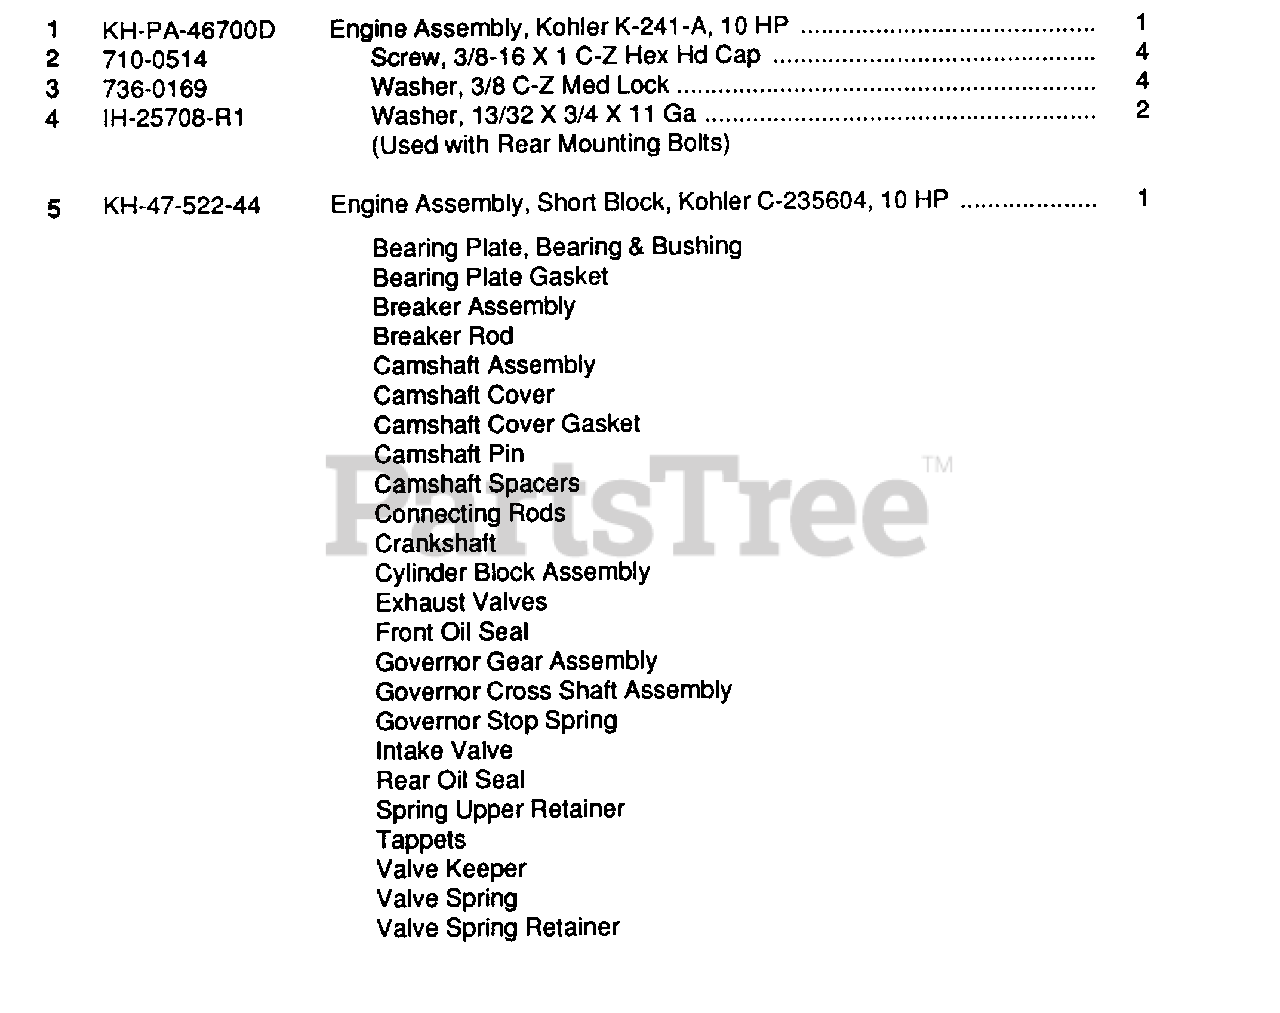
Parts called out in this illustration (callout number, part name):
1	Engine Assembly, Kohler K-241-A, 10 HP
2	Screw, 3/8-16 X 1 C-Z Hex Hd Cap
3	Washer, 3/8 C-Z Med Lock
4	Washer, 13/32 X 3/4 X 11 Ga
5	Engine Assembly, Short Block, Kohler C-235604, 10 HP
